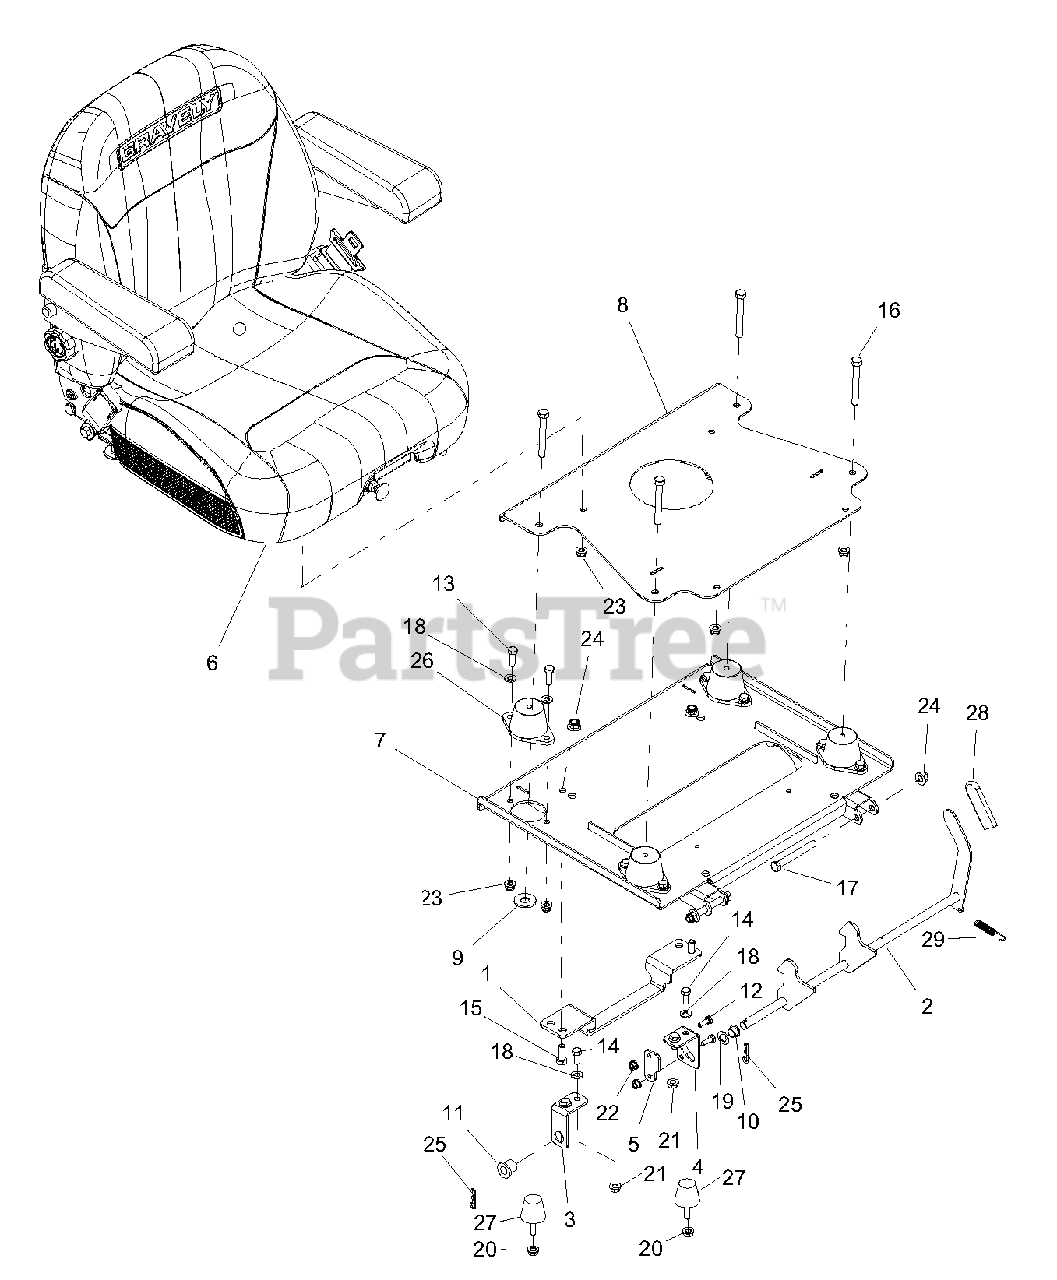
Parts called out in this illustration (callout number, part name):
1	BRKT, SEAT LATCH
2	WMT, SEAT LATCH
3	MOUNT, SEAT LATCH - RH
4	MOUNT, SEAT LATCH - LH
5	RETAINER-SEAT LATCH
6	SEAT, AIR SUSPENSION
7	WLDMT, SEAT ISO MOUNTING
8	WLDMT, SEAT MOUNTING
9	WLDMT, SEAT RETAINER
10	BSHG, SPLIT NYLON
11	BUSHING, FLANGE NYLON
12	BLT-HEX .25-20X.75 GR5 YWZC
13	BLT-HEX .31-18X1.00 GR5 YWZC
14	BLT-HEX .31-18X.75 GR5 YWZC
15	BLT-HEX .38-16X1.00 GR5 YWZC
16	BLT-HEX .38-16X3.0 GR5 FTD YWZ
17	BLT-HEX .38-16X3.25 GR5 YWZC
18	WSHR-FL-STL.344X.688X.065YWZC
19	WSHR-FL-STL .520X.827X.062 YWZC
20	NUT-SPNLK-FLG .312-18 YWZC
21	NUT, LK-TOP-FLG .312-18 YWZC
22	NUT, LK-TOP-FLG .25-20 YWZC
23	NUT-LK-NYL-FLG .31-18 YWZC
24	NUT-LK-NYL-FLG .38-16 YWZC
25	PIN-HAIR INT .08X.38X1.42 YWZC
26	MOUNT, ISOLATOR
27	BUMPER, STUD MOUNTED CONE SHAPED
28	GRIP-VINYL-YELLOW .125 x 1.0 x 3.0
29	SPRG, TENSION .043X.44X3.31 WLD 5.8
